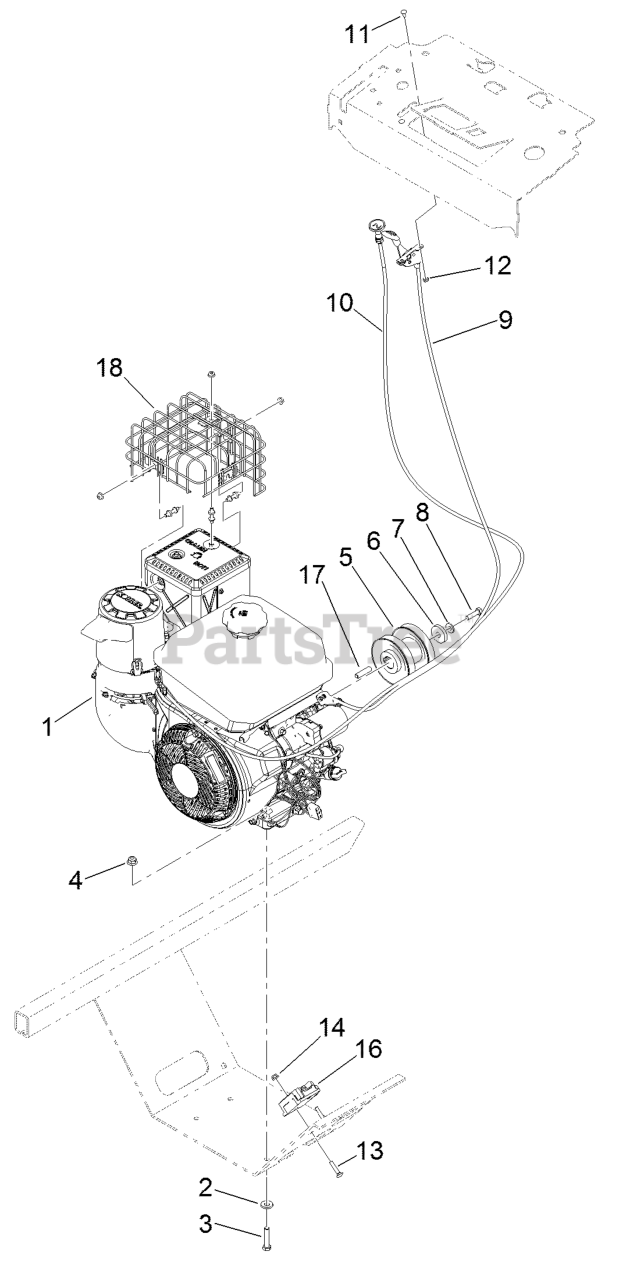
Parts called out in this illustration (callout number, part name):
1	Engine-Kohler, Ch440
2	Washer-Belleville
3	Screw-HH
4	Nut-HF, NI
6	Washer-Clutch
7	Washer-Spring
8	Screw-HH
9	Control-Throttle
10	Cable-Choke, Push/Pull
11	Bolt-CARR
12	Nut-Lock, NI
13	Screw-CARR
16	Regulator
17	Key-Square, 7Mm
18	Kit-Muffler Birdcage
